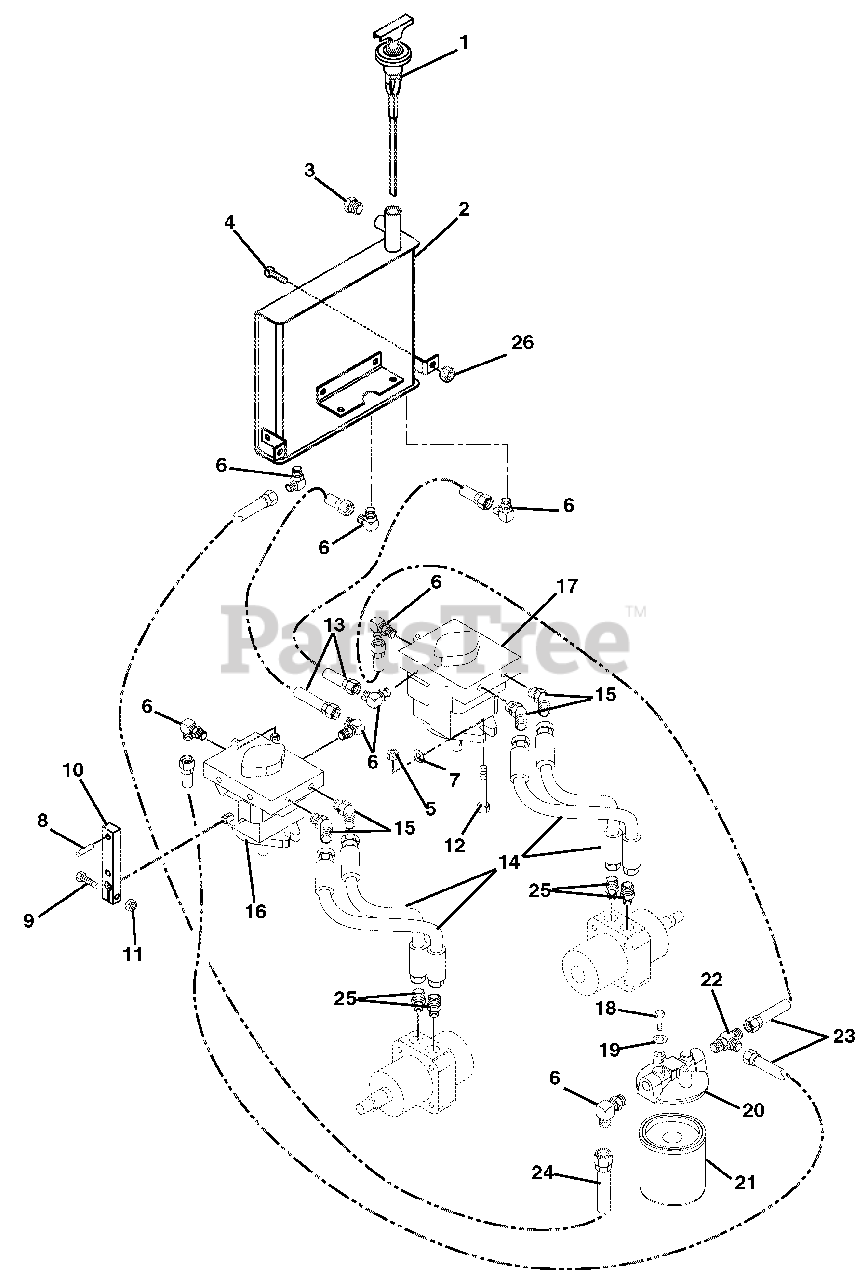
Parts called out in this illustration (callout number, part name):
1	Dipstick, Hydraulic Tank
2	Tank Assembly, Hydraulic
3	Plug, Breather .38"
4	Bolt-Hex .38-16 x 1.00 Grade 5
5	Nut-Nylon-Locking .44-14
6	Fitting, Hydraulic
7	Washer-Flat-Steel .43 x 1.00 x .16
8	Pin-Dowel .312 x 1.25
9	Bolt-Hex .25-20 x 1.25 Grade 5
10	Arm, Pump Actuating
11	Nut-Locking-Nylon .25-20
12	Bolt-Hex .44-14 x 1.50 Grade 5
13	Hose Hydraulic
14	Hose,Hydraulic
15	Fitting,Hydraulic
16	Pump, Hydraulic Right Hand
17	Pump, Hydraulic Left Hand
18	Bolt-Hex .25-20 x .50 Grade 5
19	Washer-Locking .25 x .062 Regular
20	Head, Filter
21	Filter- Oil
22	Fitting,Hydraulic Tee
23	Hose,Hydraulic
24	Hose,Hydraulic
25	Adapter, Face Seal 10 x 8.625 O-Ring
26	Nut-Locking-Nylon .38-16
